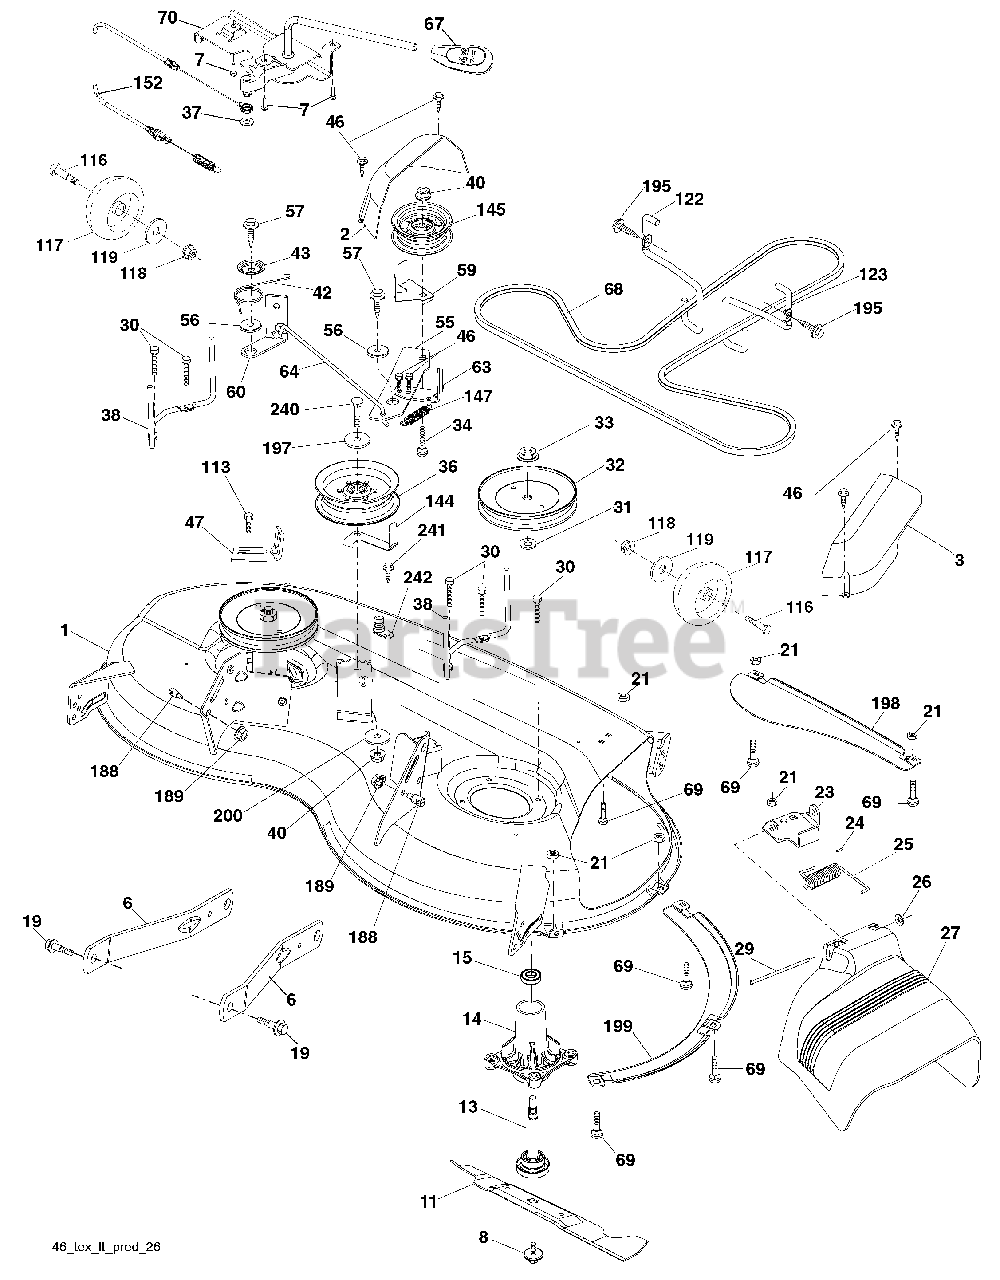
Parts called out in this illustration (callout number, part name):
1	Mower Housing
2	Cover Mandrel RH
3	Cover Mandrel LH
6	Arm Suspension
7	Screw #10 x 0.750 BOS Thread
8	Bolt/Washer asm 7/16-20 unf
11	Blade Mower
13	Shaft Assembly, Mandrel
14	Housing, Mandrel
15	Bearing, Ball, Mandrel
19	Bolt, Shoulder
21	Nut
23	Bracket, Deflector
24	Cap, Sleeve
25	Spring, Torsion, Deflector
26	Nut, Push
27	Shield, Deflector
29	Rod, Hinge
30	Screw Thdrol Rolling Wsh Hd
31	Washer, Spacer
32	Pulley, Mandrel
33	Nut, Toplock, Flanged
34	Bolt Carr Sh. 3/8-16 x 1-1/2 Gr. 5
36	Pulley, Idler, 4.50 RAW
37	Washer 13/32 x 13/16 x 16 Ga.
38	Keeper Belt LH Mandrel
40	Nut, Lock Flg. 3/8-16 unc
42	Spring Trosion Brake
43	Spring Torsion Retainer
46	Screw
47	Bracket Clutch Cable
55	Arm, Idler
56	Spacer, Retainer
57	Screw Hexwsh Thd 3/8-16 x 1
59	Guard, Tuv Idler (94)
60	Arm Brake Mower LH
63	Arm Brake Mower
64	Linkage Brake
67	Handle, Clutch Cable
68	V-Belt
69	Bolt
70	Clutch Asm.
113	Screw 5/16-18
116	Bolt, Shoulder
117	Wheel, Gauge
118	Nut Centerlock 3/8-16 unc
119	Washer 13/32 x 1-1/4 x 12 Ga.
122	Keeper Belt Eng. LH
123	Keeper Belt Eng. RH
144	Keeper Belt
145	Pulley Idler Primary
147	Spring Return
152	Cable Clutch Manual w/Spr.
188	Stud Fastener
189	Nut Lock Hex Flange
195	Screw 3/8-16 x 3/4
197	Washer 13/32 x 13/16 x 12 Ga.
198	Baffle Center Front
199	Baffle Front RH
200	Washer 13/32 x 1 x 1/2 11 Ga.
240	Bolt 3/8-16 unc x 2-1/4 Gr. 5
241	Screw TT #10-32.5 3/8 Flange
242	Port, Washout
242	Mandrel Assembly
242	Replacement Mower, Complete
